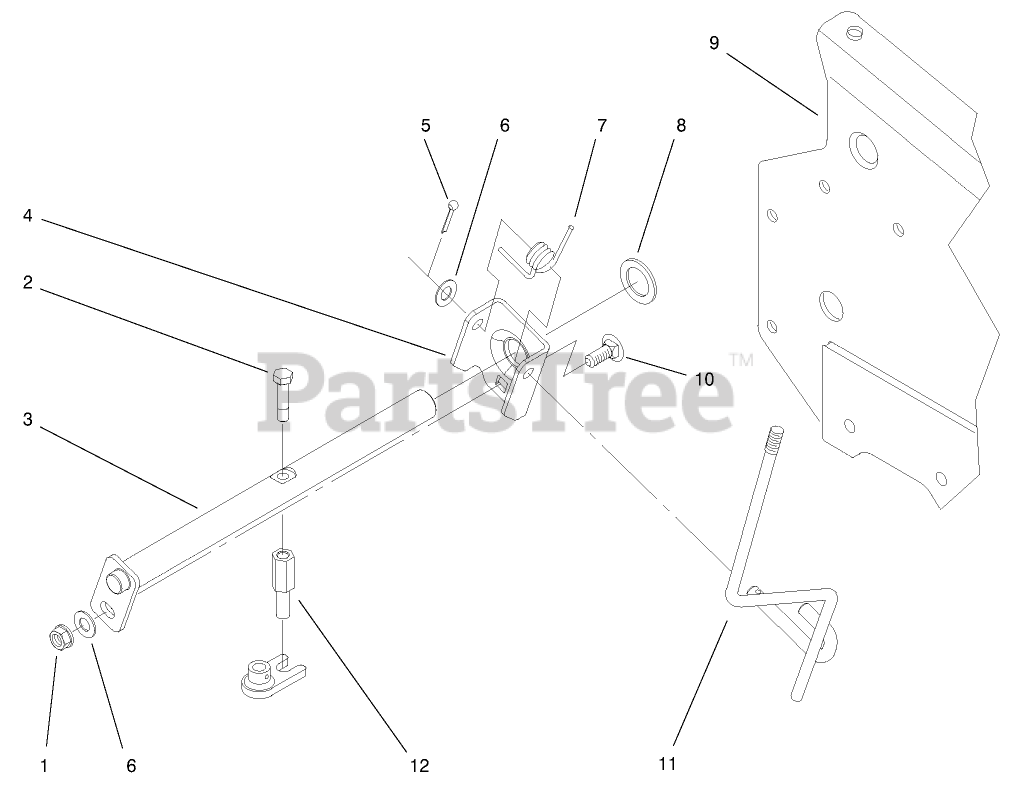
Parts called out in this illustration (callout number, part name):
1	NUT-LOCK, NI
2	SCREW-THREAD LOCKING
3	SHIFT ROD ASM
4	BRACKET-PIVOT
5	PIN-COTTER
6	WASHER-FLAT
7	SPRING-TORSION
8	SPACER
10	SCREW-CARR
11	LEVER-SHIFT
12	ROD-PIVOT, SHIFT
